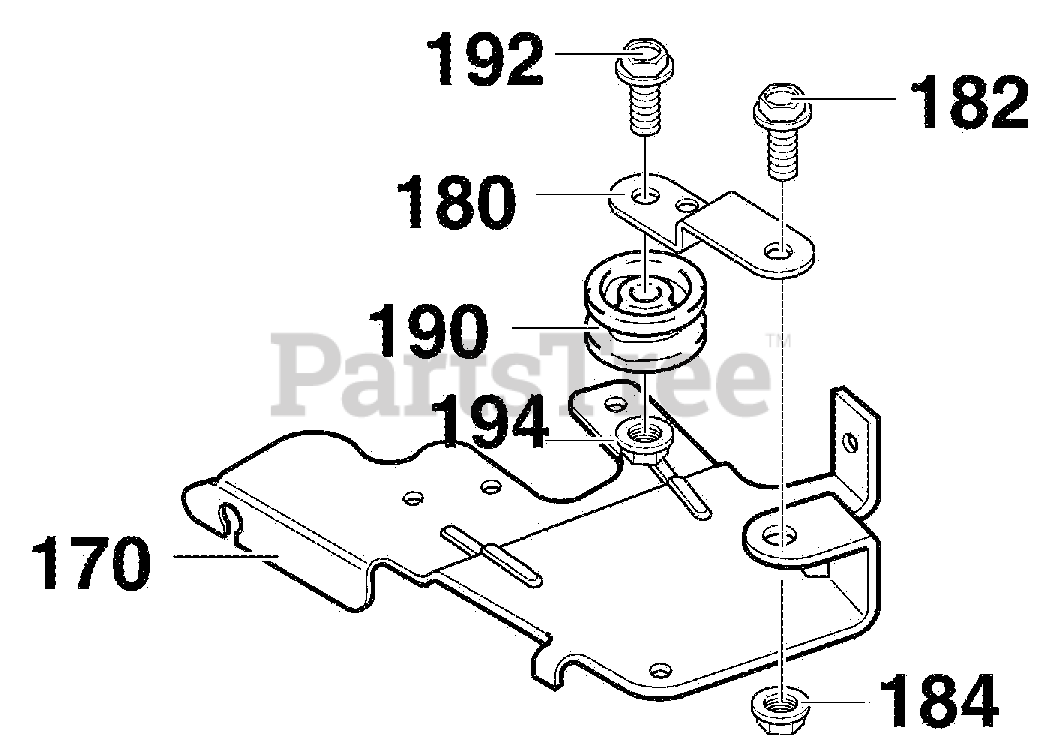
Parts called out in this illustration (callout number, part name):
170	BRACKET, Transmission
180	Idler Arm
182	BOLT, HHSH 3/8-16
184	NUT, 3/8-16
190	PULLEY, Idler
192	SCREW, 5/16-18 x 1.13
194	NUT, 5/16-18 Wdfllk
